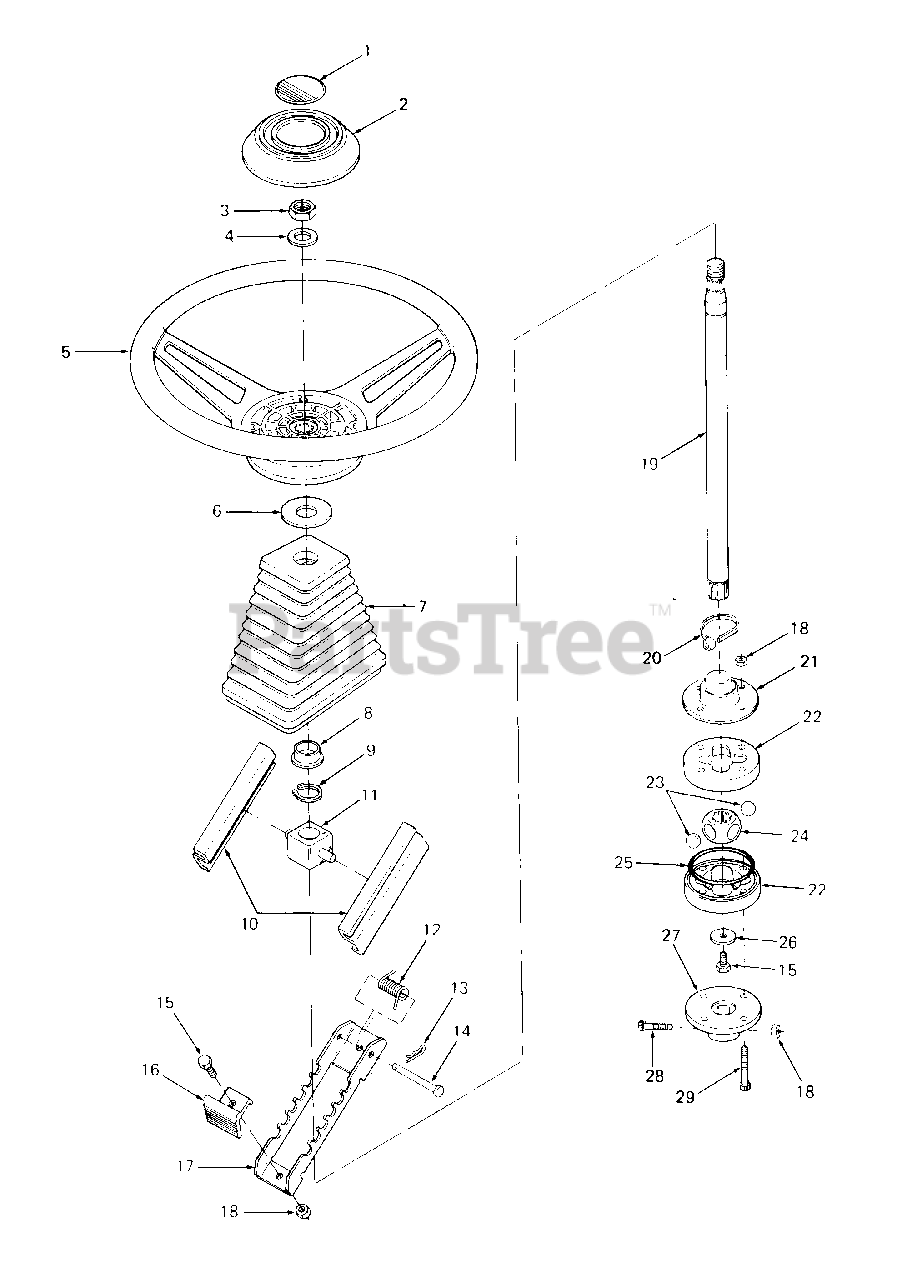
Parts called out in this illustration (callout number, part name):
1	Label, Steering Cap
2	Cap, Steering Wheel
3	Nut, Hex Jam, 5/8-18
4	Washer, Flat, .640 X 1.24 X.06 Thk HDN
5	Wheel, Steering
6	Washer, Flat, .758 X 2.0 X.030 Thk
7	Boot, Steering Shaft
8	Bearing, Flange
9	Ring, Snap
11	Bushing, Shaft Guide
12	Spring-Tilt, Torsion
13	Pin, Internal Cotter
14	Pin, Clevis, .25 Dia X 2.38 Lg
15	Screw., Hex Cap, 1/4-20 X.50 Lg GR5
16	Button, Tilt Control
17	Plate, Tilt Control
18	Nut, Hex Patch Lock, 1/4-20
19	Shaft, Upper Steering, 16.75 Lg
20	Strap, Tie 1
21	Boot, Coupling
22	Coupling, Drive w/O-Ring Groove
23	Ball, Steel, 5/8 Dia Chrome
24	Hub, Drive 1
25	O-Ring, 2.489 X.070
26	Washer, Flat, .265 X 1.0 X .030 Thk HDN
27	Adapter, Steering
28	Screw, Socket Hd Cap, 1/4-20 X 1. 12 Lg
29	Screw, Socket Hd Cap, 1/4-20 X 1.75 Lg
